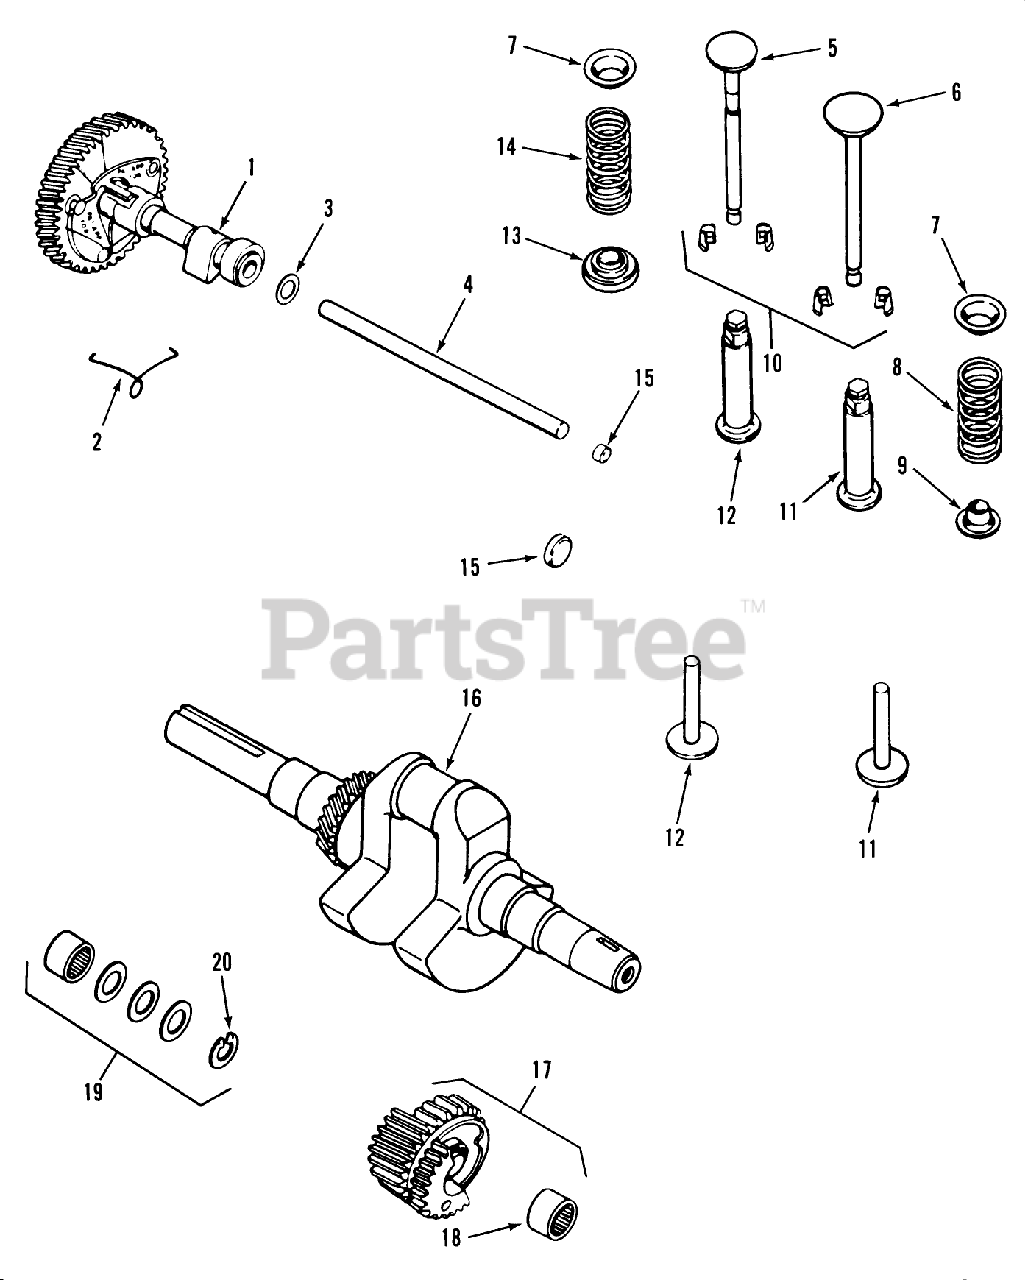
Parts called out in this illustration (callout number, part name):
1	VNDR# 25-757-13
2	KOHLER 47-089-01
3	KOHLER 275066
3	KOHLER 275067
4	KOHLER 47-380-09
5	KOHLER 235838
5	KOHLER 210223
6	KOHLER 235008
6	KOHLER 235582
7	KOHLER 235011
8	KOHLER 235010
8	KOHLER 235168
9	KOHLER 230011
10	KOHLER 41-755-10
11	KOHLER D-235327
12	KOHLER D-235327
13	KOHLER 52-413-01
14	Exhaust Valve Spring 310
14	KOHLER 235168
15	KOHLER X-702-3
16	KOHLER 47-142-02
16	KOHLER 47-142-16
17	KOHLER 45-142-21
17	KOHLER 45-043-03
18	KOHLER 47-030-01
19	KOHLER 47-755-01
20	KOHLER X-269-34
